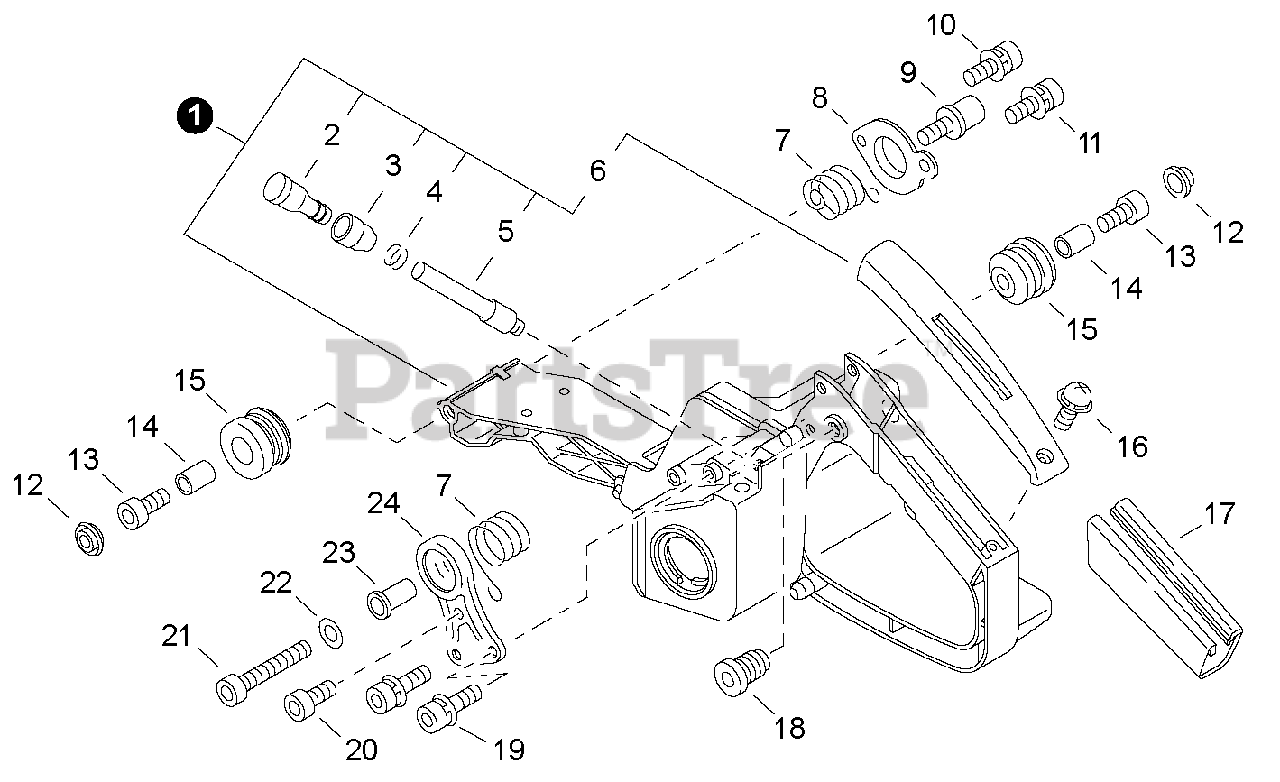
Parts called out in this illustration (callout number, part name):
1	HANDLE ASSY - REAR
2	VENT, FUEL TANK
3	COVER, VENT
4	CLIP - 6.5
5	PIPE - VENT
6	COVER, HANDLE
9	STUD, THREADED
10	SCREW - 4X8
11	SCREW - 5X14
12	CAP, CUSHION
13	SCREW - 5X25
14	COLLAR - 5
15	CUSHION
16	SCREW - 4X14
17	GRIP, HANDLE
19	SCREW - 5X14
20	SCREW - 5X8
21	SCREW - 5×35
22	WASHER - 5
23	COLLAR - 5
24	BRACKET, CUSHION
